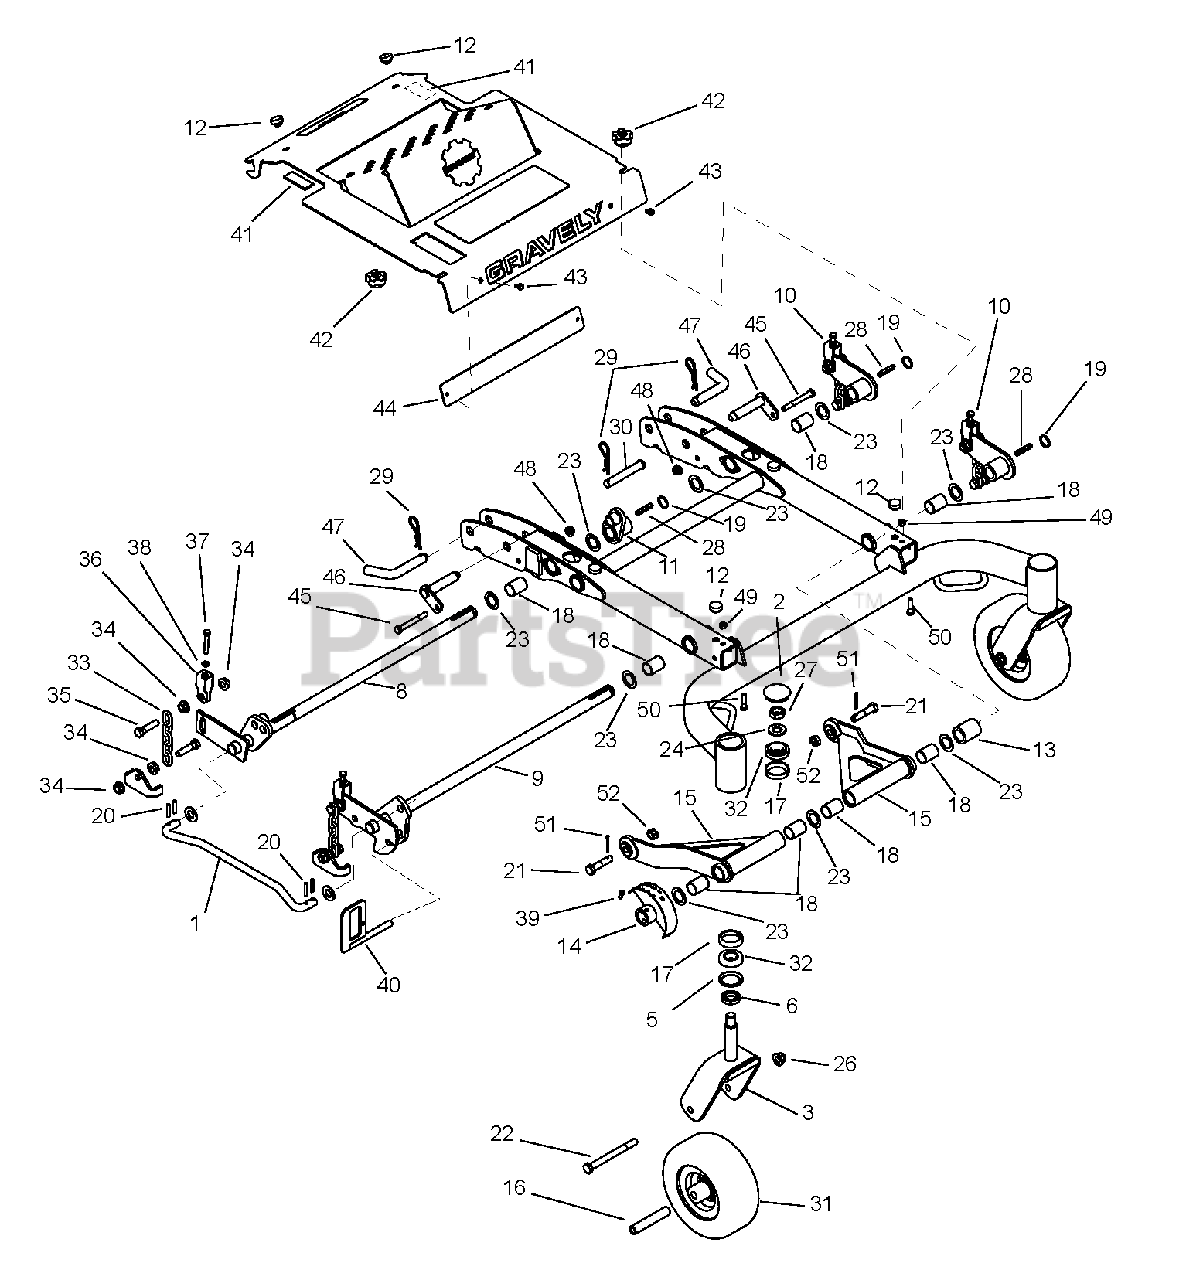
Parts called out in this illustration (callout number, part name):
1	Rod, Lift Assist 16.35
2	Cap, Dust
3	Weldment, Caster Fork (Outfront)
4	Weldment, Carrier Frame (Outfront)
5	Bearing, Seal 1.5 x 2 x .18
6	Spacer, 1.005 x 1.5075 x .375
7	Weldment, Carrier Foot Plate
8	Weldment, Shaft, Deck Lift
9	Weldment, Shaft, Deck Lift
10	Weldment, Lift Arm
11	Weldment, Mower Lift To Cylinder Arm
12	Bumper, Rubber Snap In
13	Spacer, 1.0ID x 1.5OD x 1.81 Lining
14	Cut Indicator Red
15	Weldment, Mower Mounting Arm
16	Bearing, .532 x .750 x 4.06
17	Bearing, Cup 1.980 x .420
18	Bushing, 1.00 ID x 1.125 OD x 1.50 LG
19	Ring, Retaining-External 1.00 x .078
20	Pin, Roll .250 x 1.25 Stainless Steel
21	Bolt, Hex .50-13 x 2.00
22	Bolt, Hex .50-13 x 5.50
23	Washer, Hardened-Thrust 1.00 x 1.55 x .03
24	Washer, Flat Steel .812 x 1.50 x .135 YWZC
25	Washer, Flat Steel .656 x 1.31 x .095 YWZ
26	Nut, .50-13 Nyloc Flange
27	Nut, Jam Center-Lock .75-16
28	Key, Straight .25 x 1.75 x .25
29	Pin, Hair-Internal .15 x 2.937
30	Pin, Clevis .625 x 4.0
31	Wheel Assembly 9.00 x 3.50
32	Bearing, Cone with Grease
33	Chain, Link
34	Nut, Spinlock Flange M12-1.75
35	Bolt, Hex M12-1.75 x .50 Class 8.8
36	Bracket, Deck Leveling
37	Bolt, Hex .312-18 x 2.00 FTH
38	Nut, Jam .312-18
39	Screw, Set .25-20 x .50 YZ EP 80
40	Pin, Deck Tilt (shipped loose in literature package)
41	Tape, Foam .12 x 1.0 x 2.50
42	Knob, Clamping .312-18
43	Screw, Tapping Hex Washer HD .25-20-.50
44	Plate, Bumper
45	Bolt, Hex .38-16 x 3.25
46	Weldment, Carrier Frame Mounting Pin
47	Pin, Bent .75 Dia.
48	Nut, Nyloc Flange .318-16
49	Nut, Locking-Center .31-18
50	Bolt, Hex .31-18 x 1.25
51	Pin, Cotter
52	Nut, .50-13
